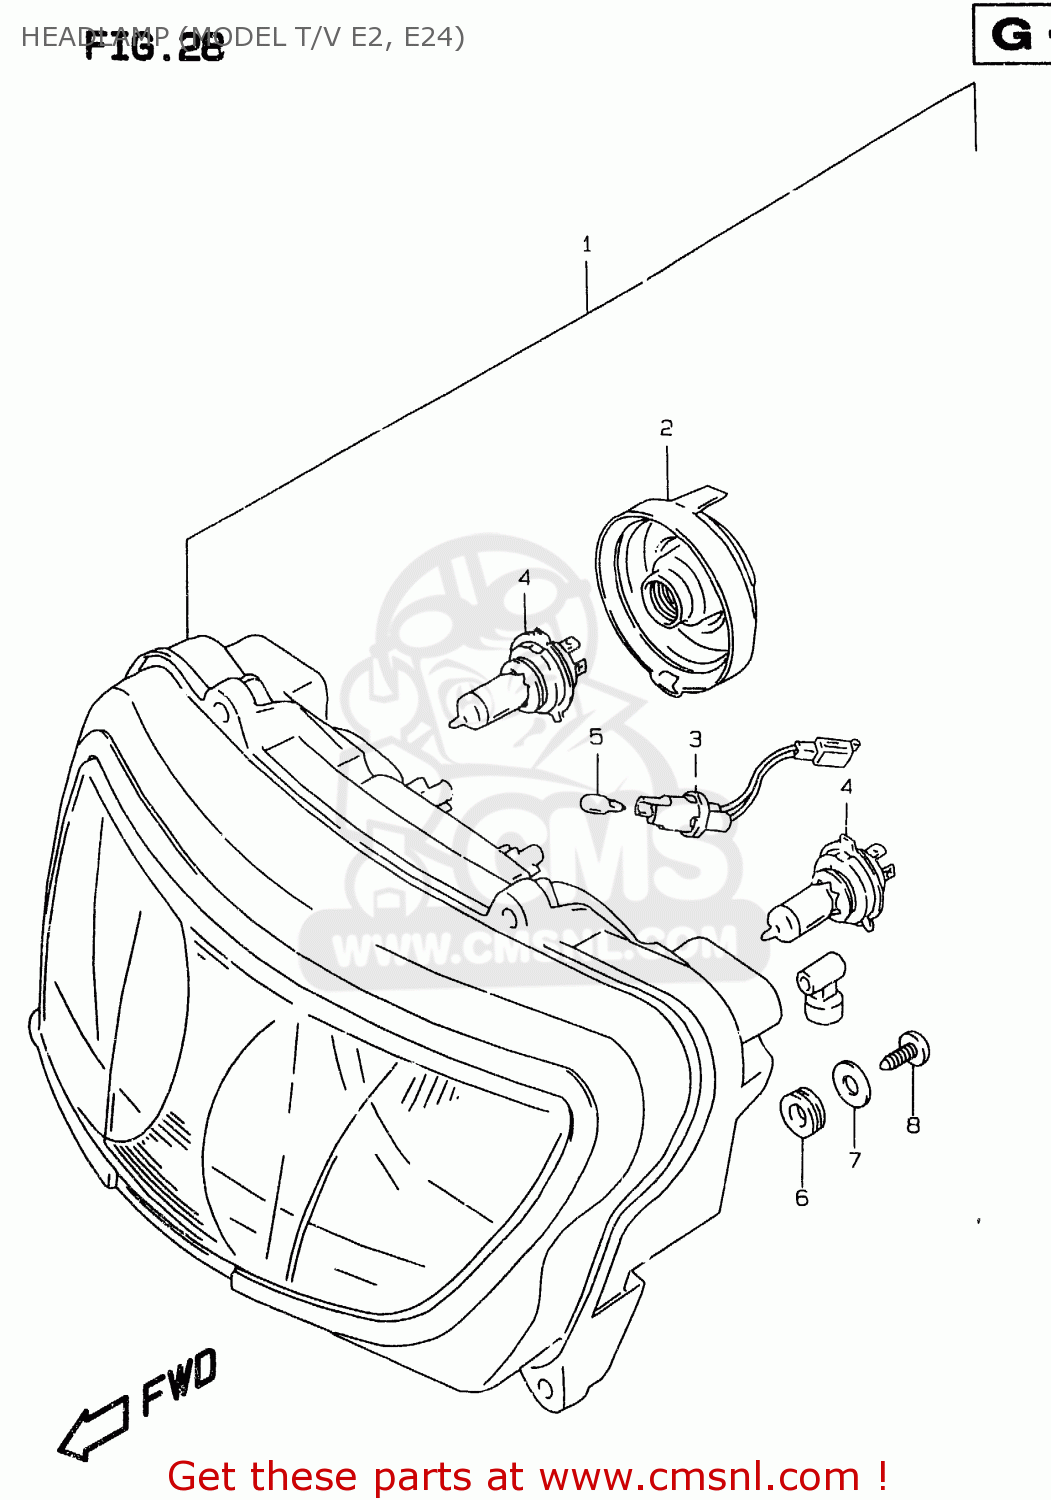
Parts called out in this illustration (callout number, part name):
1	HEADLAMP ASSY
2	COVER,SOCKET
3	SOCKET ASSY
4	BULB(12V55/50W)
5	BULB(12V5W)
6	CUSHION,HEADLAMP
7	WASHER(5.5X18X1)
8	SCREW,SIDE HOL
